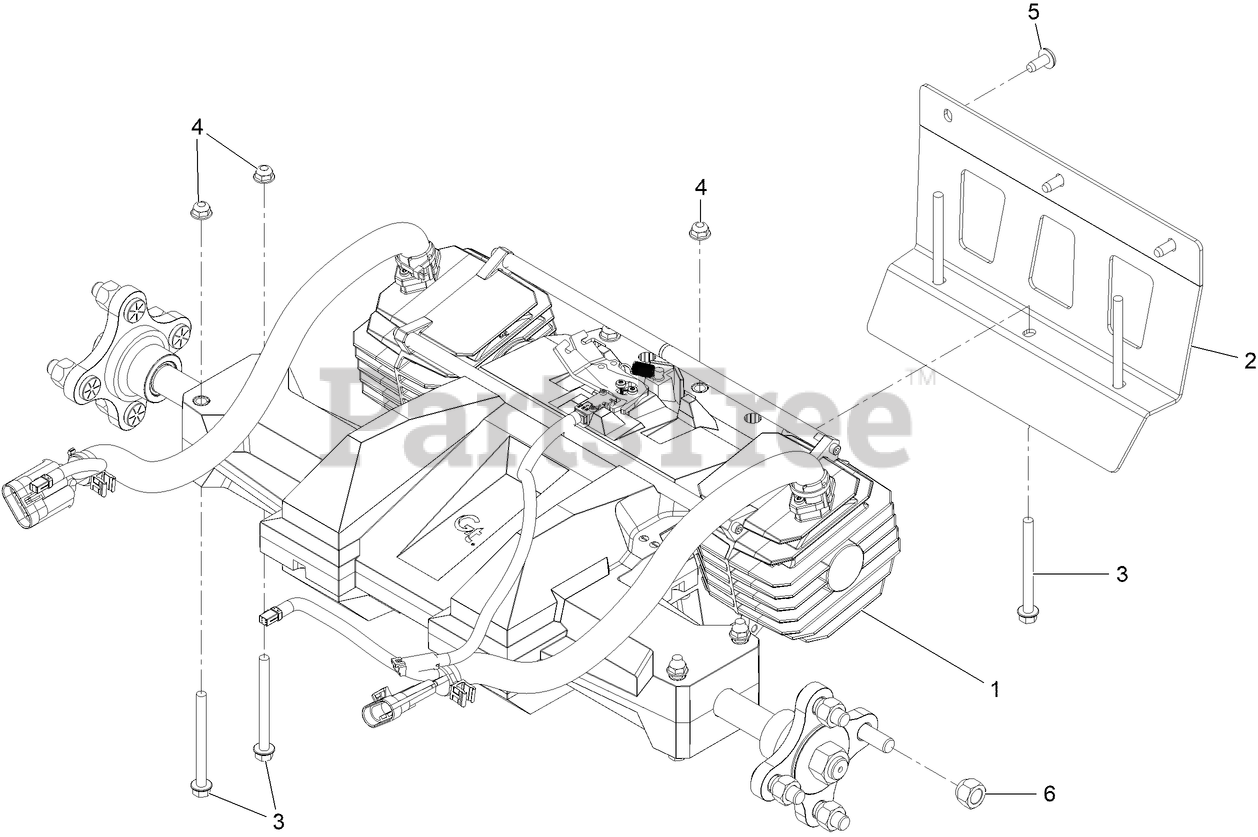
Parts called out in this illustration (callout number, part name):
1	TRANSAXLE-ELECTRIC, 18
2	BRACKET-TRANSMISSION
3	SCREW-HH
6	NUT-LUG
